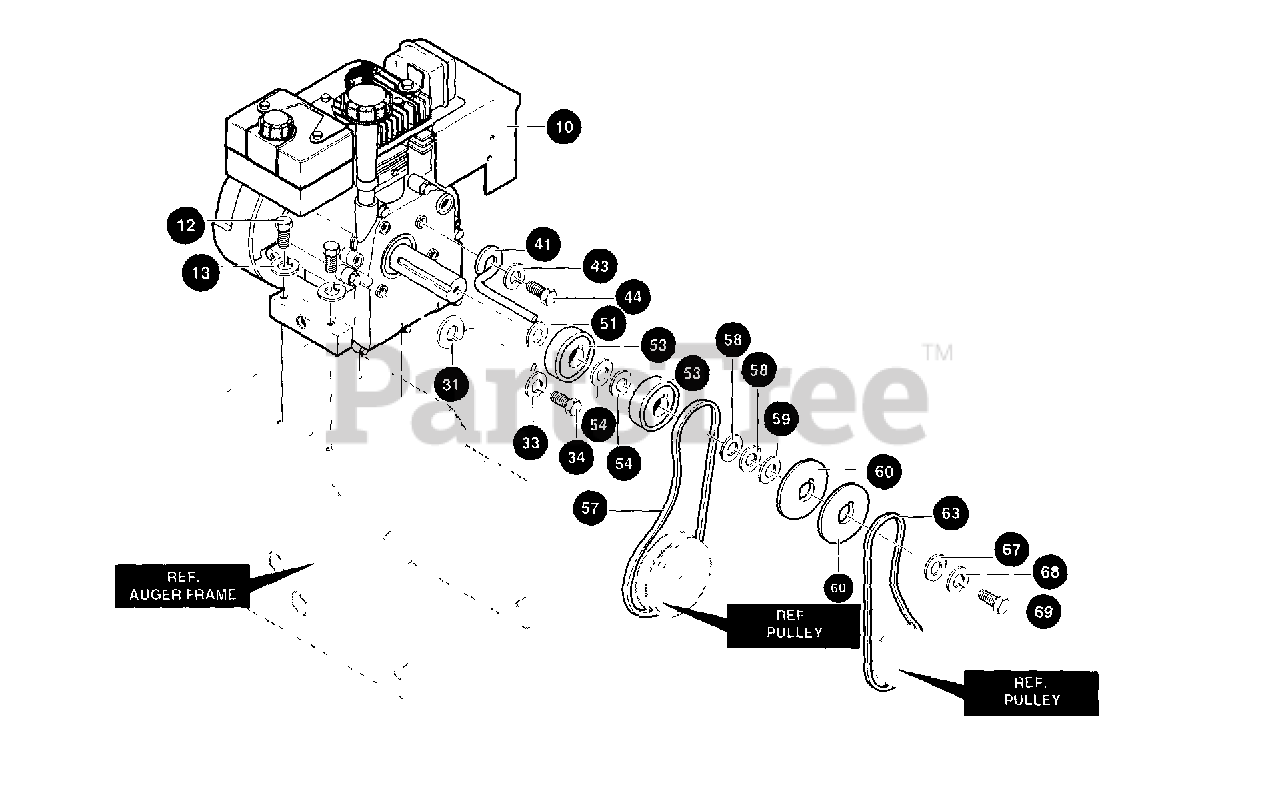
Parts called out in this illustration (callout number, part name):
10	ENGINE, 7 HP
12	SCREW, 5/16-18
13	WASHER, .328 X .60 X .09
31	GUIDE, ROD BELT RH
33	WASHER, .328 X .60 X .09
34	SCREW, 5/16-24 X .625
41	GUIDE, ROD BELT RH
43	WASHER, .326 X .60 X .09
44	SCREW, 5/16-24 X .625
51	WASHER, CRANKSHAFT
53	PULLEY, HALF
54	FLATWASHER .752 X .91 X .02
57	BELT, V 3L 33.13LG
58	FLATWASHER .765 X 1.12 X .06
59	SPACER, SLEEVE
60	PULLEY, ENGINE
63	BELT, V 4L 38.1
67	FLATWASHER
68	WASHER, .393 X .68 X .10
69	SCREW, 3/8-24 X 1.00
